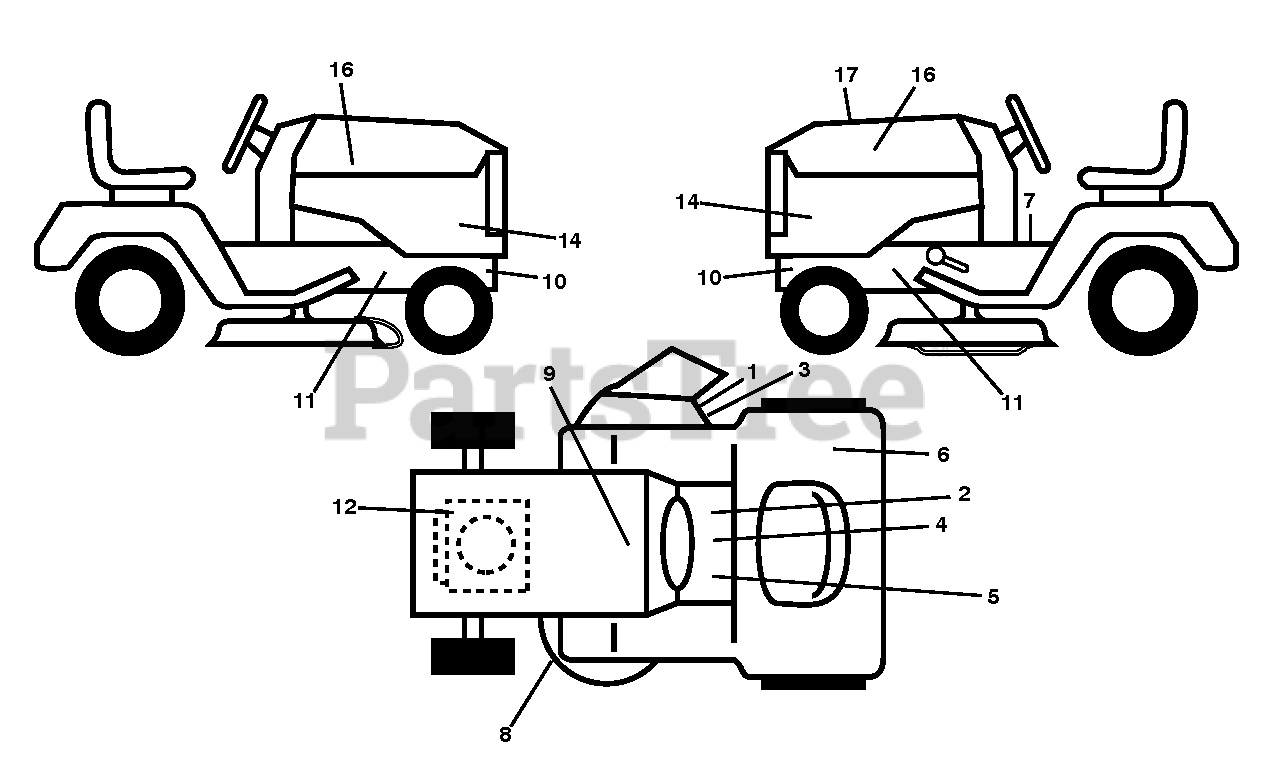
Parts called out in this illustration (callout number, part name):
1	DECAL.INTERNATIONL.CUTFINGER
2	DECAL
3	DECAL, DEFLECT WARNING
4	DECAL PARK BRAKE
5	LABEL
6	Decal, Fender 100 DB/CE
7	DECAL
8	DECAL V BELT SCHEMATIC
9	DECAL BTRY SYMBOLS
12	DECAL
16	RP.DECAL.BADGE.170MM.TEXTLOGO
